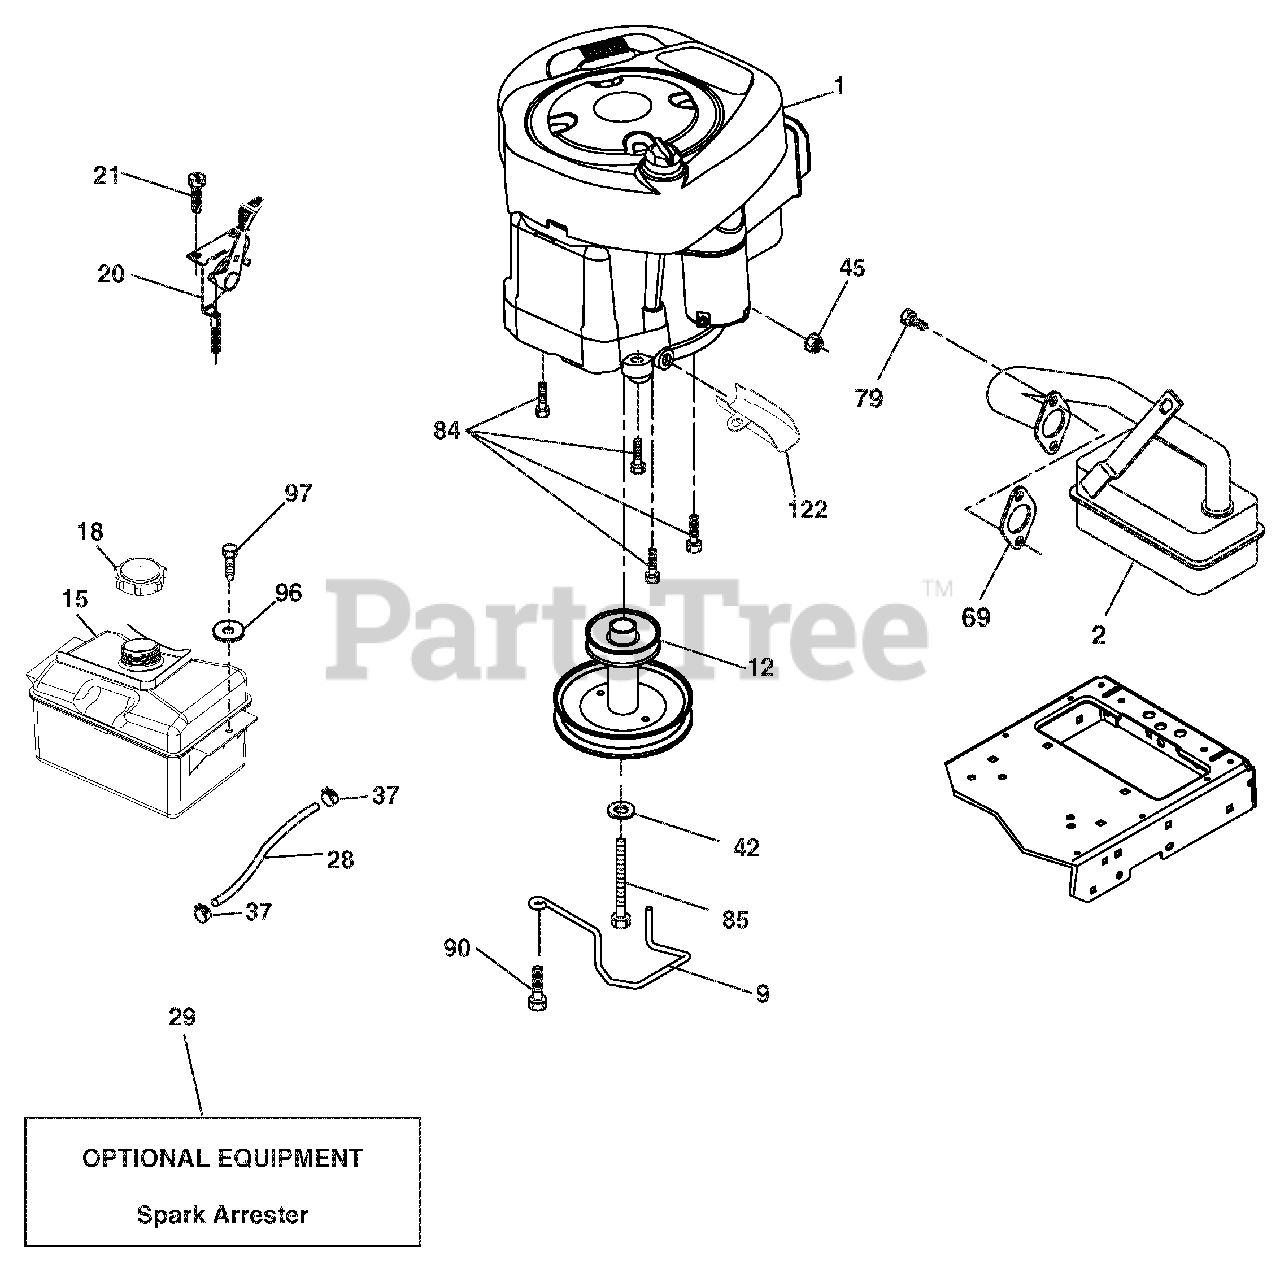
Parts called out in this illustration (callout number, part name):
1	ENGINE BRIGGS MODEL NO. 31P677-1373-B1 (ORDER PARTS FROM ENGINE MANUFACTURER)
2	Muffler Exhaust B&S
9	KEEPER.BELT.ENGINE.3.25"NSTL
12	PULLEY.ENGINE
15	TANK.FUEL.FRT.N/CAP.1.5GAL.DAP
18	CAP ASM.FUEL.TOP.125/2.5.LTTEX
20	CONTROL.TH/CK.COBRA.BS.EEC.428
28	LINE.FUEL.22"FRONT.EMIS.CA.LP
29	KIT.SPARK ARRESTOR(392390 B&S)
37	CLAMP.HOSE.BLK.
42	WASHER.LOCK.HVY HLCL.SPR.7/16
45	Nut, Keps Hex 1/4-20 unc
69	Gasket Eng 1 313 Id Tin Plated
79	SCREW.SOCKET HD.5/16-18 X .75
84	Screw 3/8-16 x <
85	BOLT.HEX.7/16-20X4XGR5-1.5THR.
90	SCREW.3/8-16X1.SMGML.TAP/R.BLK
96	WASHER.9/32 X 7/8 X 16GA.
97	SCREW.HEXWSH.THDROL.1/4-20X3/4
122	Extension Drain Oil
